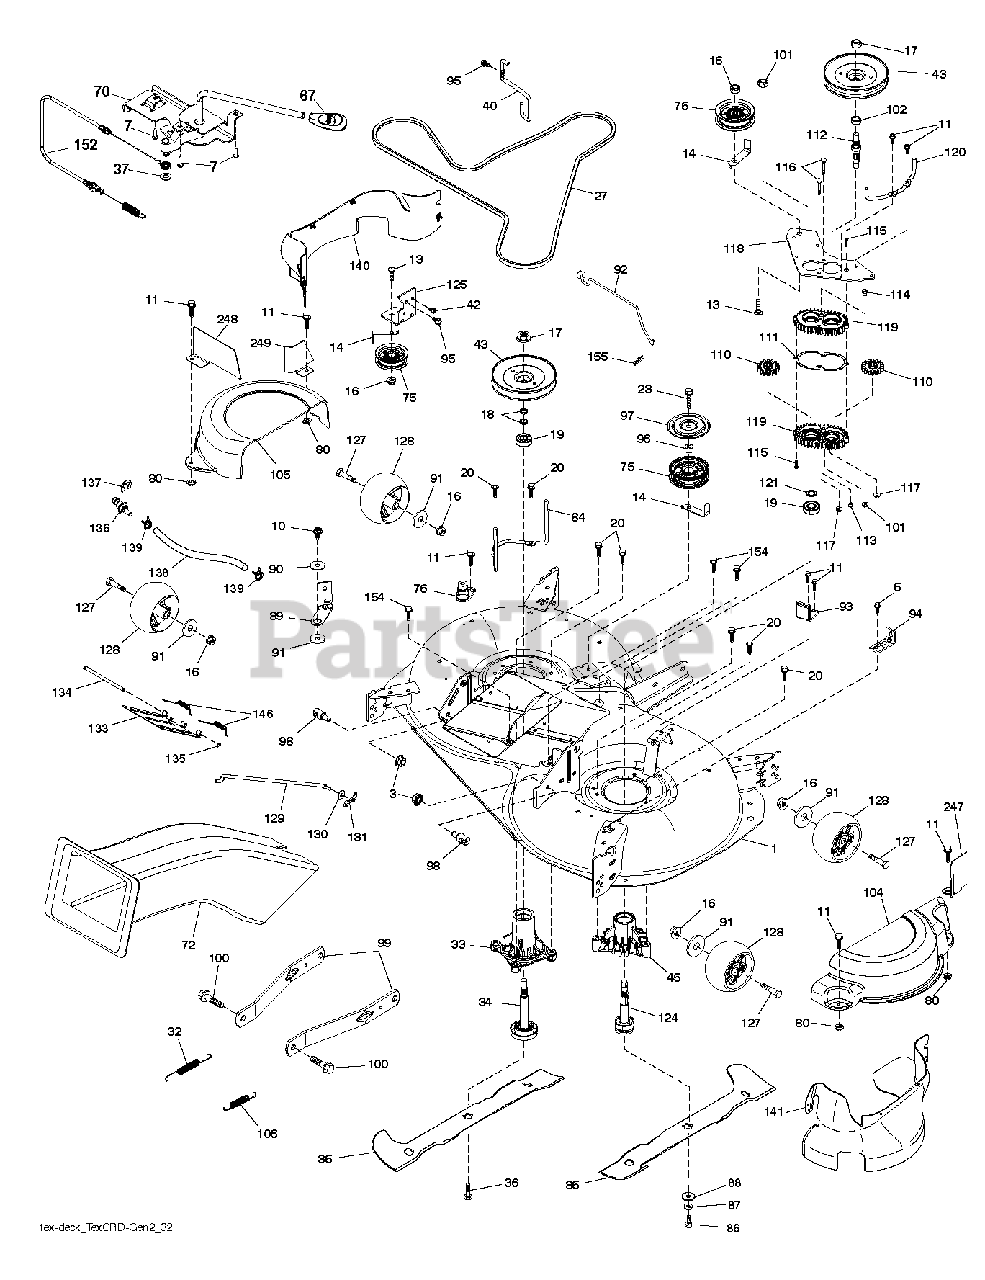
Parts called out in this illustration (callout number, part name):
3	NUT LOCK HEX FLANGE 5/16-18
5	BOLT.5/16HEX.WHS.HD
7	SCREW.#10 X 0.750.BOS THREAD
10	SCREW 3/8-16X1
11	SCREW.1/4-20X5/8
13	BOLT.3/8-16X1.50
14	KEEPER, BELT IDLER
16	NUT LOCK FLG 3/8-16 UNC
17	NUT.FLANGE.LOCK.TOP
18	WASHER.SPACER.MANDREL
20	SCREW, WASHER HEAD
23	SCREW LT
32	SPRING RETURN
36	BOLT.WASHER.ASM.7/16-2
40	KEEPER BELT ENGINE LH
42	SCREW
67	HANDLE.CLUTCH.CABLE.LT
70	CLUTCH.ASM.MANUAL.YT.PREDATORQ
75	FLAT IDLER PULLEY
80	PALNUT 1/4
87	LOCKWASHER
88	WASHER.BLADE
89	ARM BRAKE MOWER
90	SPACER.RETAINER
94	BRKT.CLUTCH.CABLE
95	SCREW, 3/8-16X3/4
98	STUD.FASTNER.W/ANTI-ROTATE
99	ARM.SUSPENSION.MOWER.R
100	BOLT.SHOULDER
102	SPACER BEARING
106	SPRING.BRAKE.RETURN.38"
117	NUT T
127	BOLT.SHOULDER.3/8-16X3-5/8
128	WHEEL. GUAGE RALLY
130	WASHER
131	PIN.COTTER.5/16.BOW TI
135	E-RING.5/16"
137	RING CLIP
155	RETAINER M
